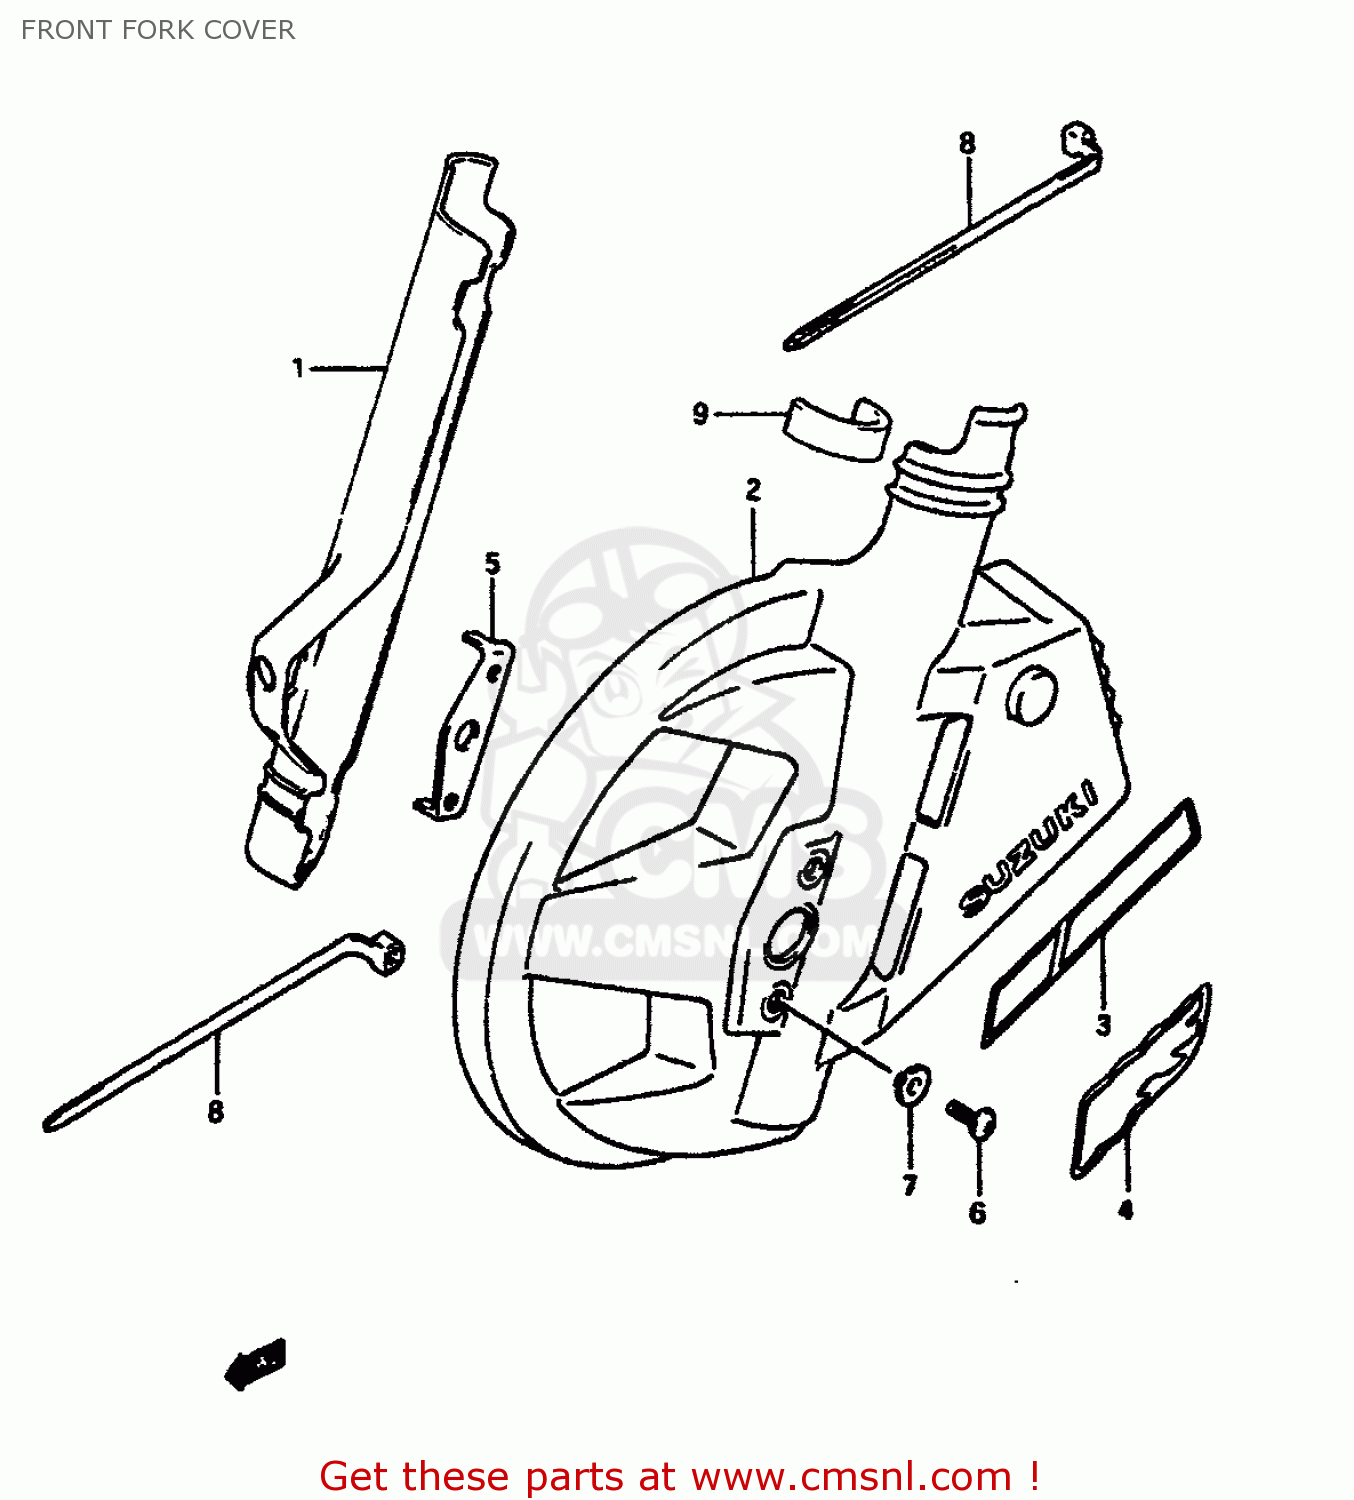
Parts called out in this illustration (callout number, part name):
1	PROTECTOR,FR FORK,R
2	PROTECTOR,FORK LH (BLUE)
3	TAPE,PROTECTOR LH
4	TAPE,PROTECTOR LH
5	PLATE,PROTECTOR SET
6	SCREW 6X12
7	WASHER
8	CLAMP
9	CUSHION
